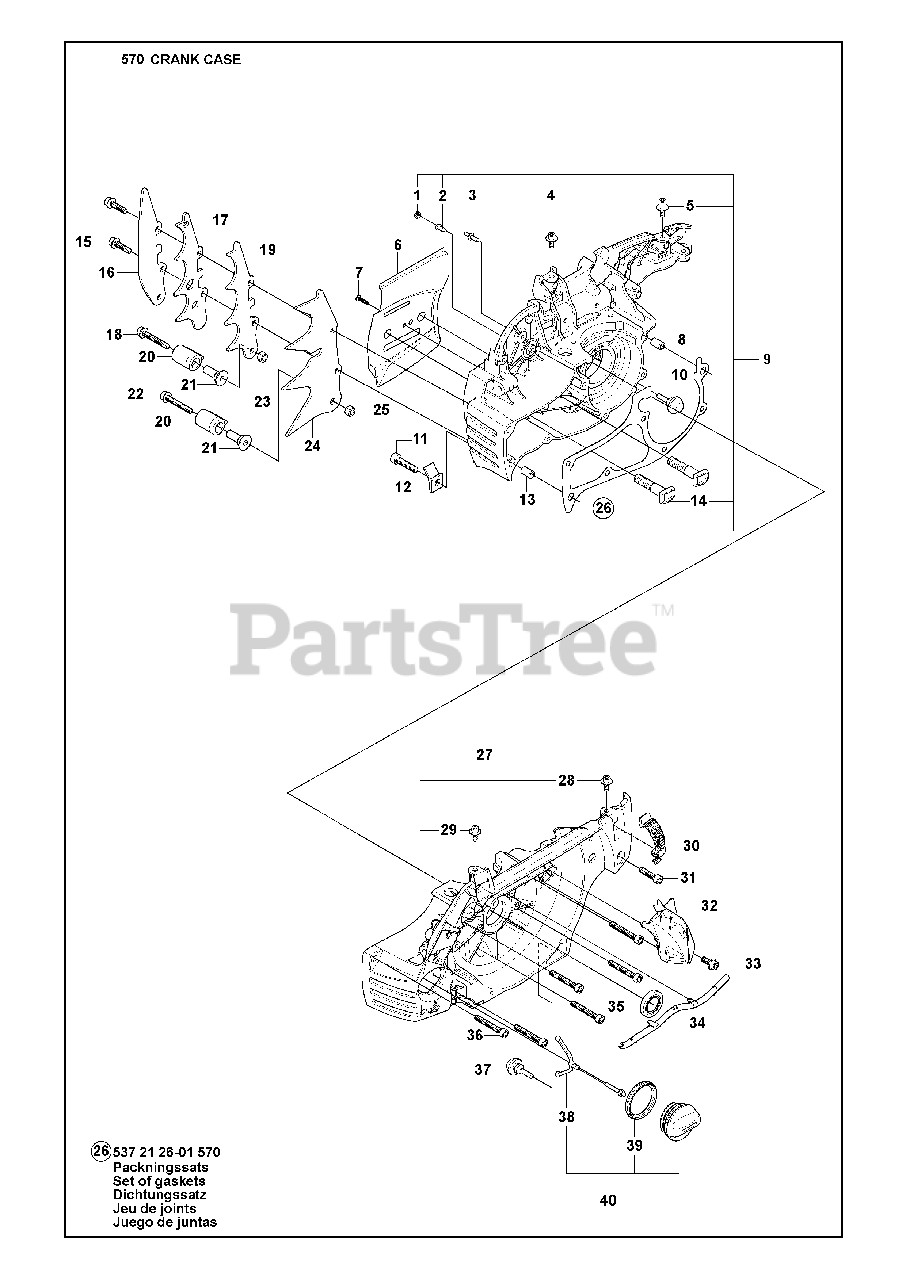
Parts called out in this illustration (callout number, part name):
1	PLUG
2	VALVE-CHECK (DUCKBILL)
4	SCREW IHSCM
5	SCREW IHSCM
9	CRANKCASE ASSY
12	CHAIN CATCHER
17	FELLING DOG
18	SCREW IHSCFM
19	FELLING DOG
21	CHAIN CATCHER
22	SCREW
24	FELLING DOG
26	GASKET SET
27	RP CRANKCASE ASSEMBLY
28	SCREW IHSCM
29	SCREW IHSCM
30	BUCKLE ORANGE
35	RADIAL SEAL
40	TANK CAP
